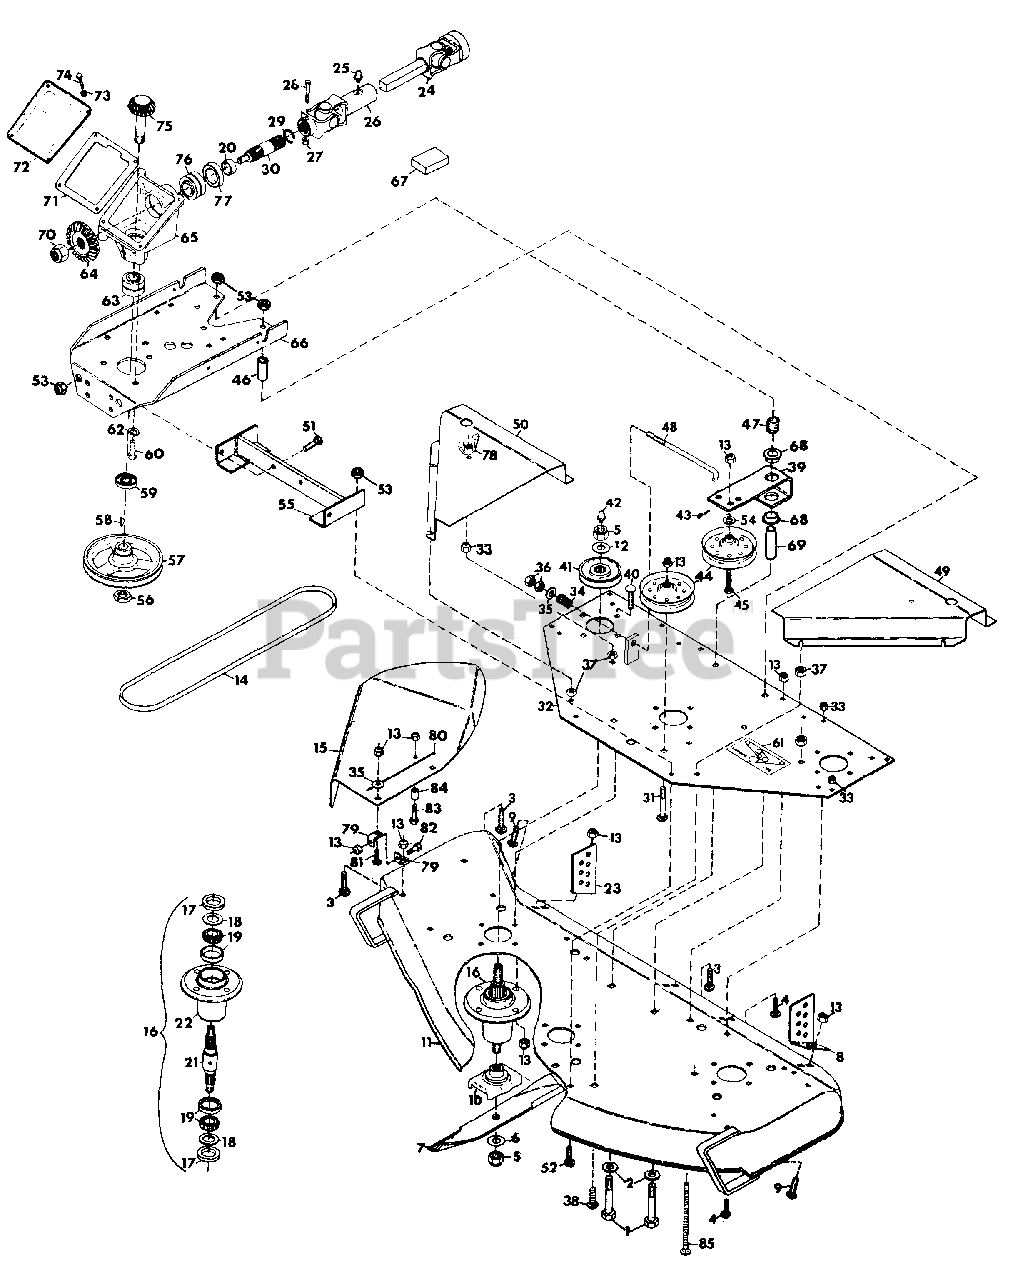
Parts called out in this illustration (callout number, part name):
1	BOLT, HEX 1/2-13X3.75
2	WASHER, FLAT .531X1.062X.095
3	BOLT, 3/8-16X.75 RD HD SQ NK
4	BOLT, 5/16-18X.75 RD HD SQ NK
5	NUT, LOCK 5/8-11
6	WASHER, FLAT .656X1.312X.095
7	BLADE
8	PLATE, REAR ADJUSTMENT
9	BOLT, HEX 3/8-16X1.25
10	CRADLE, BLADE
11	WELDMENT, 50 INCH DECK
12	WASHER, FLAT .687X1.312X.122/.146
13	NUT, LOCK 3/8-16
14	BELT, V .500X.312X126.3
15	SHIELD, SAFETY EXTENSION 50 INCH MOWER
16	ASSEMBLY, SPINDLE
17	SEAL, STEEL
18	WASHER, FLAT .975X1.970X.030
19	ASSEMBLY, BEARING
20	SPACER
21	SHAFT, SPINDLE
22	HOUSING, BEARING
23	PLATE, REAR ADJUSTMENT
24	SHAFT, PROP. SQ BAR
25	FITTING, LUBE 1/4-28
26	U-JOINT, FEMALE END
27	NUT, LOCK 1/4-20
28	BOLT, HEX 1/4-20X2
29	RING, RETAINING 1.000 SHAFT
30	SHAFT, DRIVE
31	BOLT, 3/8-16X1.75 RD HD SQ NK
32	WELDMENT, SUPPORT PLATE
33	NUT, LOCK 5/16-18
34	SPRING, COMP. TYPE 1X.78X338 LB/IN
35	WASHER, FLAT .406X.812X.065
36	NUT, HEX 3/8-24
37	NUT, JAM 5/16-18
38	BOLT, CARRIAGE 5/16-18X1.00
39	ARM, IDLER PIVOT
40	BOLT, W/8-16X1.25 RD HD SQ NK
41	SHEAVE, SPINDLE
42	FITTING, LUBE 1/8(LEFT AND RIGHT SPINDLE)
42	FITTING, LUBE .125 EXT.(CENTER SPINDLE)
43	PIN, COTTER 3/32X1.00
44	SHEAVE, IDLER
45	BOLT, HEX 3/8-16X2
46	SPACER, .510X.840X2.43
47	SPRING, COMP.
48	ROD, IDLER
49	COVER, PULLEY L.H.
50	COVER, PULLEY R.H.
51	BOLT, HEX 1/2-13X1.375
52	BOLT, HEX 1/2-13X1.25
53	NUT, LOCK 1/2-13
54	SPACER, IDLER .406X.750X.188
55	BRACKET, HEIGHT ADJUSTMENT
56	NUT, JAM 3/4-10 HEX HEAVY
57	SHEAVE, 1/2X6.50
58	KEY, WOODRUFF .188X.625 HARD
59	SEAL, OIL 1.250X1.686X.313
60	BOLT, HEX 1/2-13X1.00
61	DECAL, BELT INSTALLATION
62	WASHER, LOCK 1/2
63	ASSEMBLY, BEARING .750X1.781X1.499
64	GEAR, BEVEL
65	CASTING, GEAR BOX
66	SUPPORT, GEAR HOUSING
67	KIT, REPAIR UNIVERSAL JOINT ROCKWELL STD.
67	KIT, REPAIR UNIVERSAL JOINT NEAPCO 1605X
68	BUSHING, NYLON .760X1.00X.600
69	SPACER
70	NUT, LOCK 3/4-10
71	GASKET, GEAR HOUSING
72	COVER, GEAR HOUSING
73	WASHER, LOCK 1/4
74	BOLT, HEX 1/4-20X.50
75	SHAFT, GEAR PINION
76	ASSEMBLY, BEARING 1.000X1.980X1.243
77	SEAL, OIL 1.25X1.987X.250
78	NUT, WING 5/16-18
79	TAB, SPRING
80	STRIPE
81	BOLT, 3/8-16X1.00 RD HD SQ NK
82	BOLT, HEX 3/8-16X.875
83	BOLT, HEX 3/8-16X1.50
84	STOP, CHUTE
85	BOLT, HEX 5/16-18X3.50
NS	ASM, DRIVE 50" MOWER
NS	DECAL, DANGER HAND
NS	DECAL, DANGER FOOT
NS	DECAL, WARNING EYE
NS	DECAL, PRO MASTER-50 MOWER
